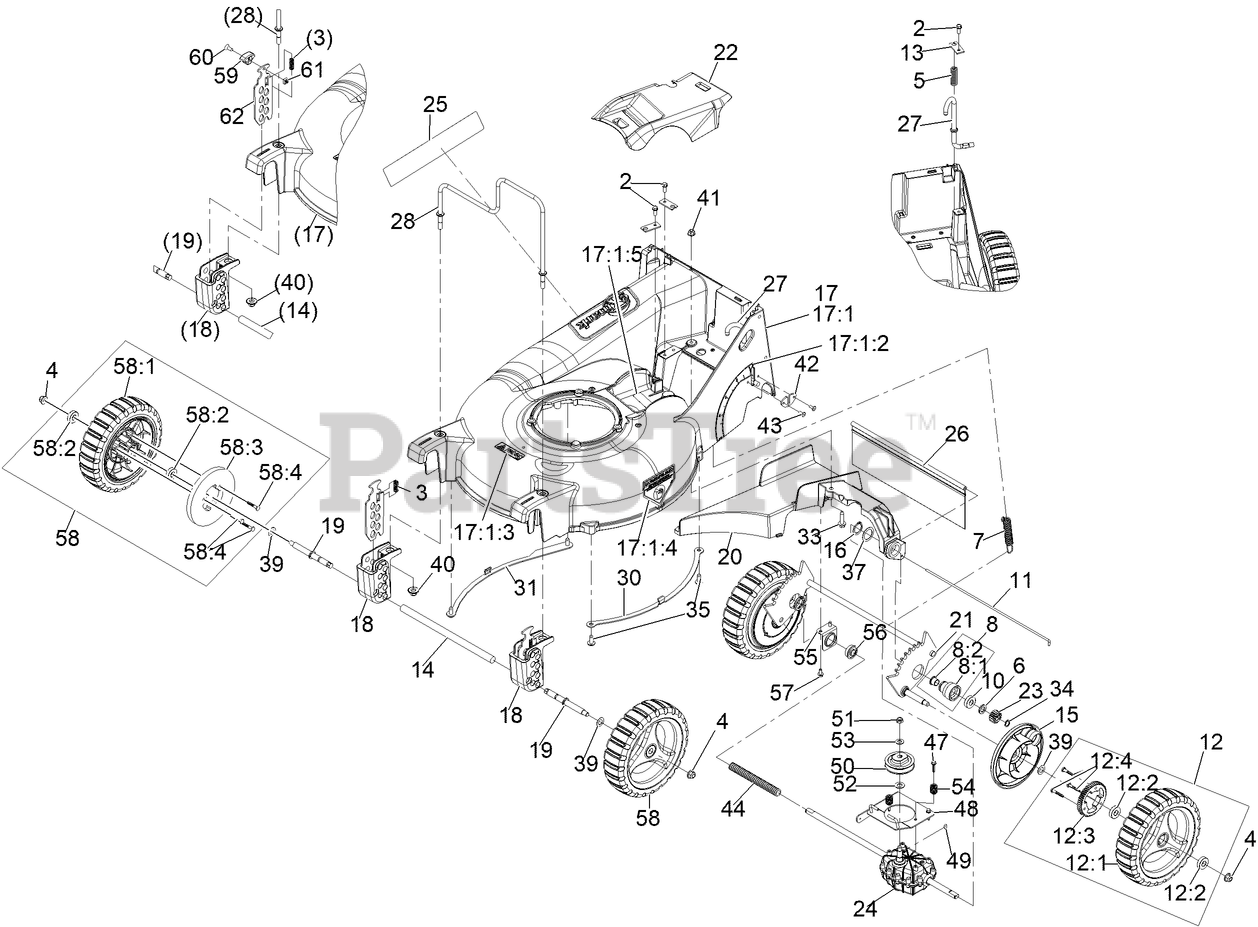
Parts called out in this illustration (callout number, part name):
2	SCREW-HWH
3	SPRING-COMPRESSION
4	NUT-HF, NI
5	SPRING-COMPRESSION
6	SPACER-BUSHING
7	SPRING-EXTENSION
8	HOUSING ASM
8:1	HOUSING-BEARING
8:2	BEARING-FLANGE
10	BEARING-BALL
11	ROD,SHIELD
12	WHEEL ASM, 9 W/GEAR
12:1	WHEEL ASM, 9
12:2	BEARING-BALL
12:3	GEAR-WHEEL, 52T
12:4	STUD-DRIVE
13	BRACKET,MOUNT
14	ROD,BUMPER
15	COVER,GEAR
16	RING-RETAINING
17	ASM-DECK EC21
17:1:2	DECAL-HEIGHT OF CUT
17:1:3	DECAL-WARNING, BLADE
17:1:4	DECAL-DANGER
17:1:5	DECAL-DANGER
18	BLOCK,FRONT QUADRANT
19	AXLE-WHEEL
20	Bracket-Transmission And Chute
21	WLD,REAR AXLE P21
22	COVER-BELT
23	GEAR-PINION, 15T
24	TRANSMISSION-HD, 4.5/1
25	Decal-Commercial 21 V-Series
26	SHIELD-TRAILING P21
27	ROD-HEIGHT ADJ P21
28	Guard-Front Motor
33	SCREW-HWHTF
34	RING-RETAINING
39	WASHER-PLAIN
40	Nut-Nyloc 3/8-16 Flg
41	NUT-HF, NI
42	PLATE,WEAR
43	RIVET-BLIND
44	COVER-SHAFT-DRIVE
47	SCREW-SPECIAL
48	TRANSMISSION PLATE ASM
49	KEY-WOODRUFF
51	NUT-HEX
52	WASHER-THRUST
53	WASHER-FLAT
54	SPRING,COMPRESSION
55	MOUNT-BEARING
56	BEARING-BALL
57	SCREW-HWH
58	ASM-Wheel W/ Weight
58:1	WHEEL ASM, 9
58:2	BEARING-BALL
58:3	WEIGHT-WHEEL
58:4	STUD-DRIVE
59	GRIP-HOC HANDLE
60	SCREW-HSFH
61	Square Nut 1/4-20,ATV CB
62	PLATE-ADJUSTER
